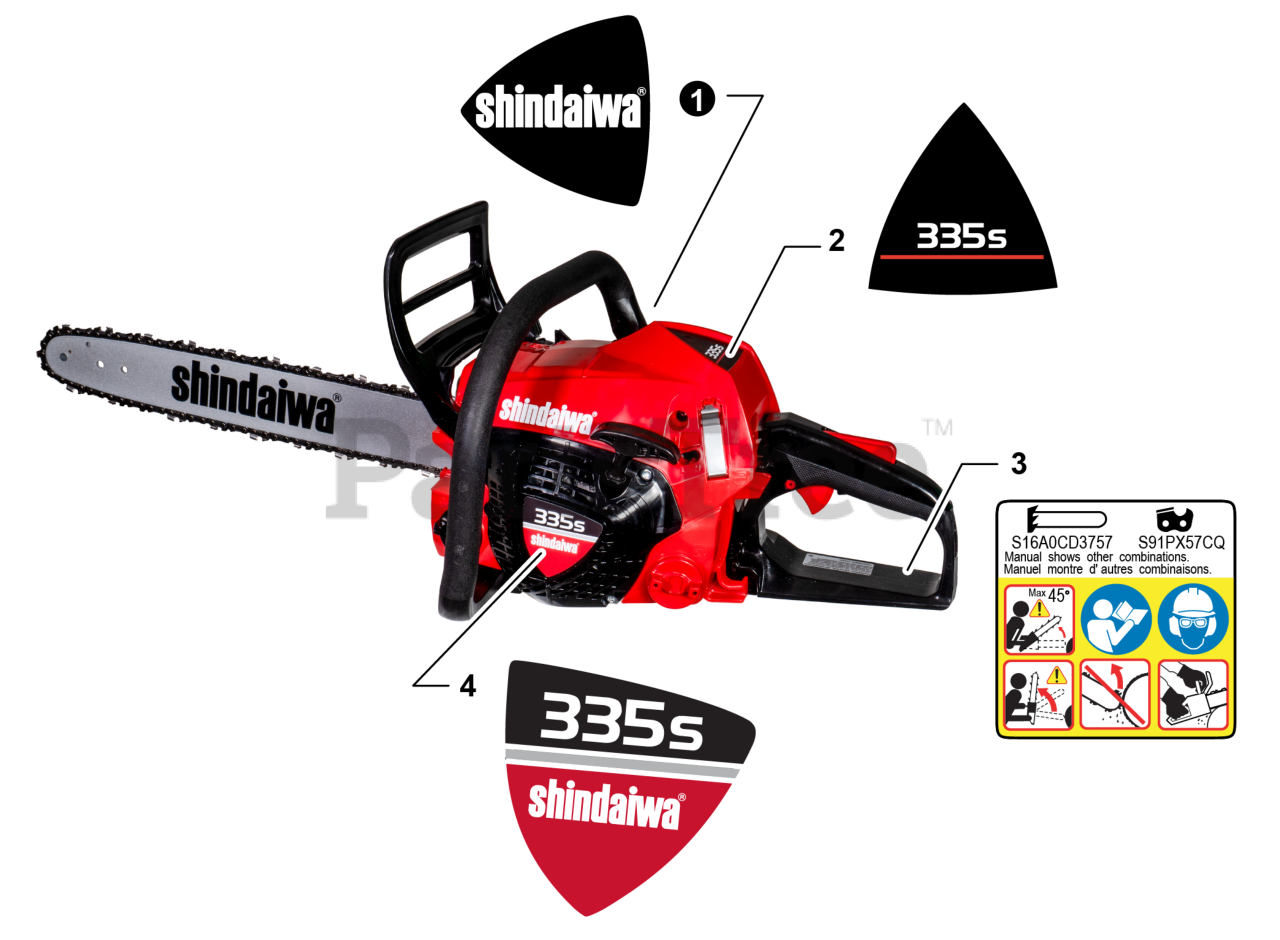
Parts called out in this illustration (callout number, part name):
1	LABEL - SHINDAIWA
2	LABEL - MODEL 335S
3	LABEL - CAUTION
4	LABEL - RECOIL STARTER
